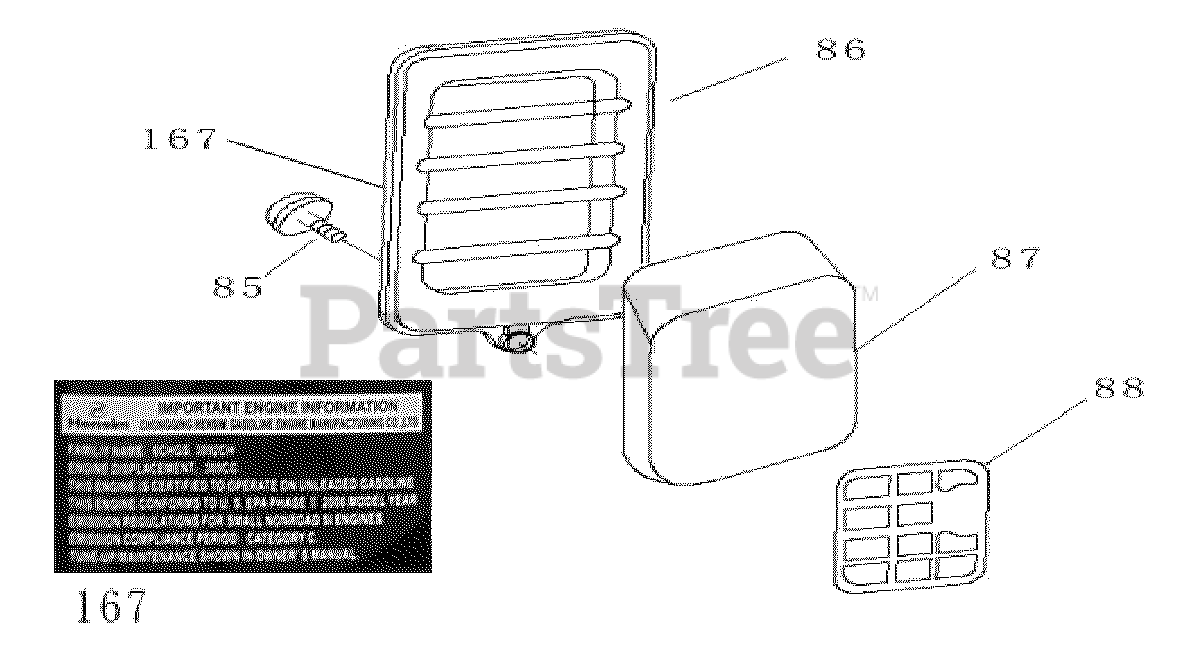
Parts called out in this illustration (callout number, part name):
85	Air cleaner bolt
86	Air filter cover
87	Air filter
88	Air filter board
167	EPA label
